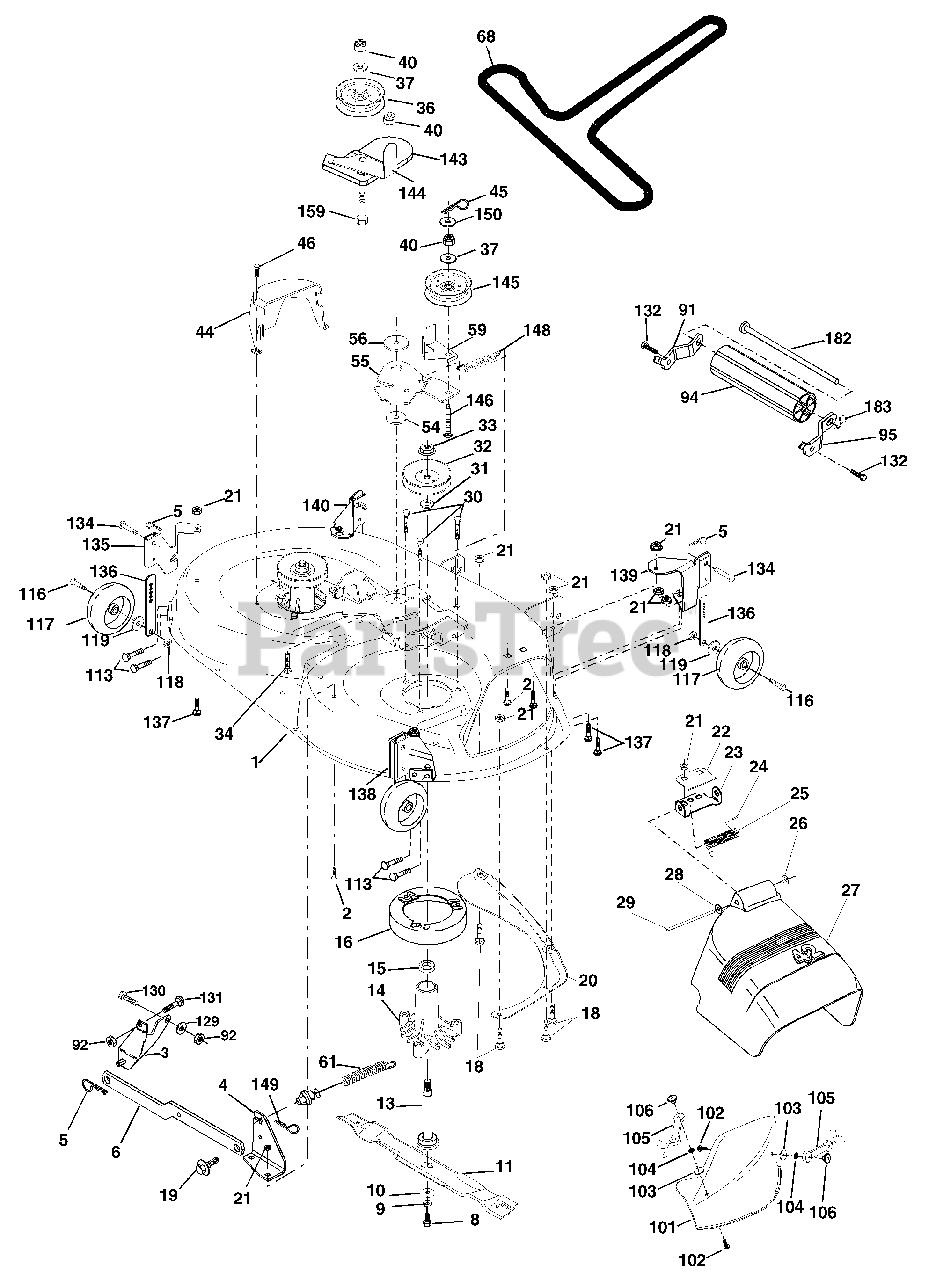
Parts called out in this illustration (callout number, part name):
1	Mower Deck Assembly, 42"
2	Bolt
3	Bracket Assembly, Sway Bar, Front
4	Bracket Sway Bar 42" Deck
5	Retainer Spring
6	Bar Sway Deck
8	Bolt, Hex 3/8-24 x 1.25 Gr. 8
9	Washer, Lock
10	Washer, Hardened
11	Blade Mower 42" High Perf.
11	Blade, Mulching
13	Shaft Assembly, Mandrel, Vented
14	Housing, Mandrel, Vented
15	Bearing, Ball, Mandrel
16	Stripper
18	Bolt, Carriage 5/16-18 x 5/8
19	Bolt, Shoulder
20	Baffle, Vortex
21	Nut Crownlock 5/16-18 UNC
22	Stiffener Bracket
23	Bracket, Deflector
24	Cap, Sleeve
25	Spring, Torsion, Deflector
27	Shield, Deflector
28	Washer 11/32 x 5/8 x 16 Ga.
29	Rod, Hinge
30	Screw Thdrol Hex
31	Washer, Spacer
32	Pulley, Mandrel
33	Nut, Toplock, Flanged
36	Pulley, Idler, Flat
37	Washer 13/32 x 13/16 x 16 Gauge
40	Nut Crownlock 3/8-16 UNC
44	Guard, Mandrel, L.H.
45	Retainer
46	Screw, Thd. Roll 1/4-20 x 5/8
54	Washer, Hardened
55	Arm, Idler
56	Spacer, Retainer
59	Guard, TUV Idler
61	Spring Ext Elect Clutch 42" Dck
91	Bracket Asm Noseroller Lh
92	Nut Lock Hex 5/16-18
94	Roller Nose 38"-50"
95	Bracket Asm Noseroller Rh
101	Mulcher Cover
102	Screw
103	Washer #10
104	Washer, Lock
105	Latch Assembly, Bagger
106	Nut, Weld
113	Screw 5/16-18 x 3/4 Tap R
116	Bolt, Shoulder
117	Wheel, Gauge
118	Nut, Centerlock 3/8-16
119	Washer 3/8 x 7/8 x 14 Gauge
129	Washer 13/32 x 13/16 x Ga.
130	Bolt Fin Hex 3/8-16unc x 1 Gr.5
131	Bolt Rdhd Sqnk 3/8-16unc x 1
132	Screw 3/8-16 x .75
134	Pin Head Rivet
135	Bracket Asm Whl GA R LH
136	Bar Adjusting GA WHL
137	Bolt Carr 5/16-18 x 5/8
138	Bracket Asm Whl GA R RH
139	Bracket Asm Whl GA F RH
140	Bracket Asm Whl GA F LH
143	Bracket Arm Idler 42"
144	Keeper Belt 42" Clutch Cable
145	Pulley Idler Flat
146	Bolt Carriage Idler
148	Spring Return Idler
149	Retainer Spring Yellow Zinc
150	Washer 9/32 x 3/4 x 16 Ga.
159	Bolt Rdhd Sqn 3/8-16 UNC x 1- 3/4
182	Rod Roller Nose
183	Retainer Spring
